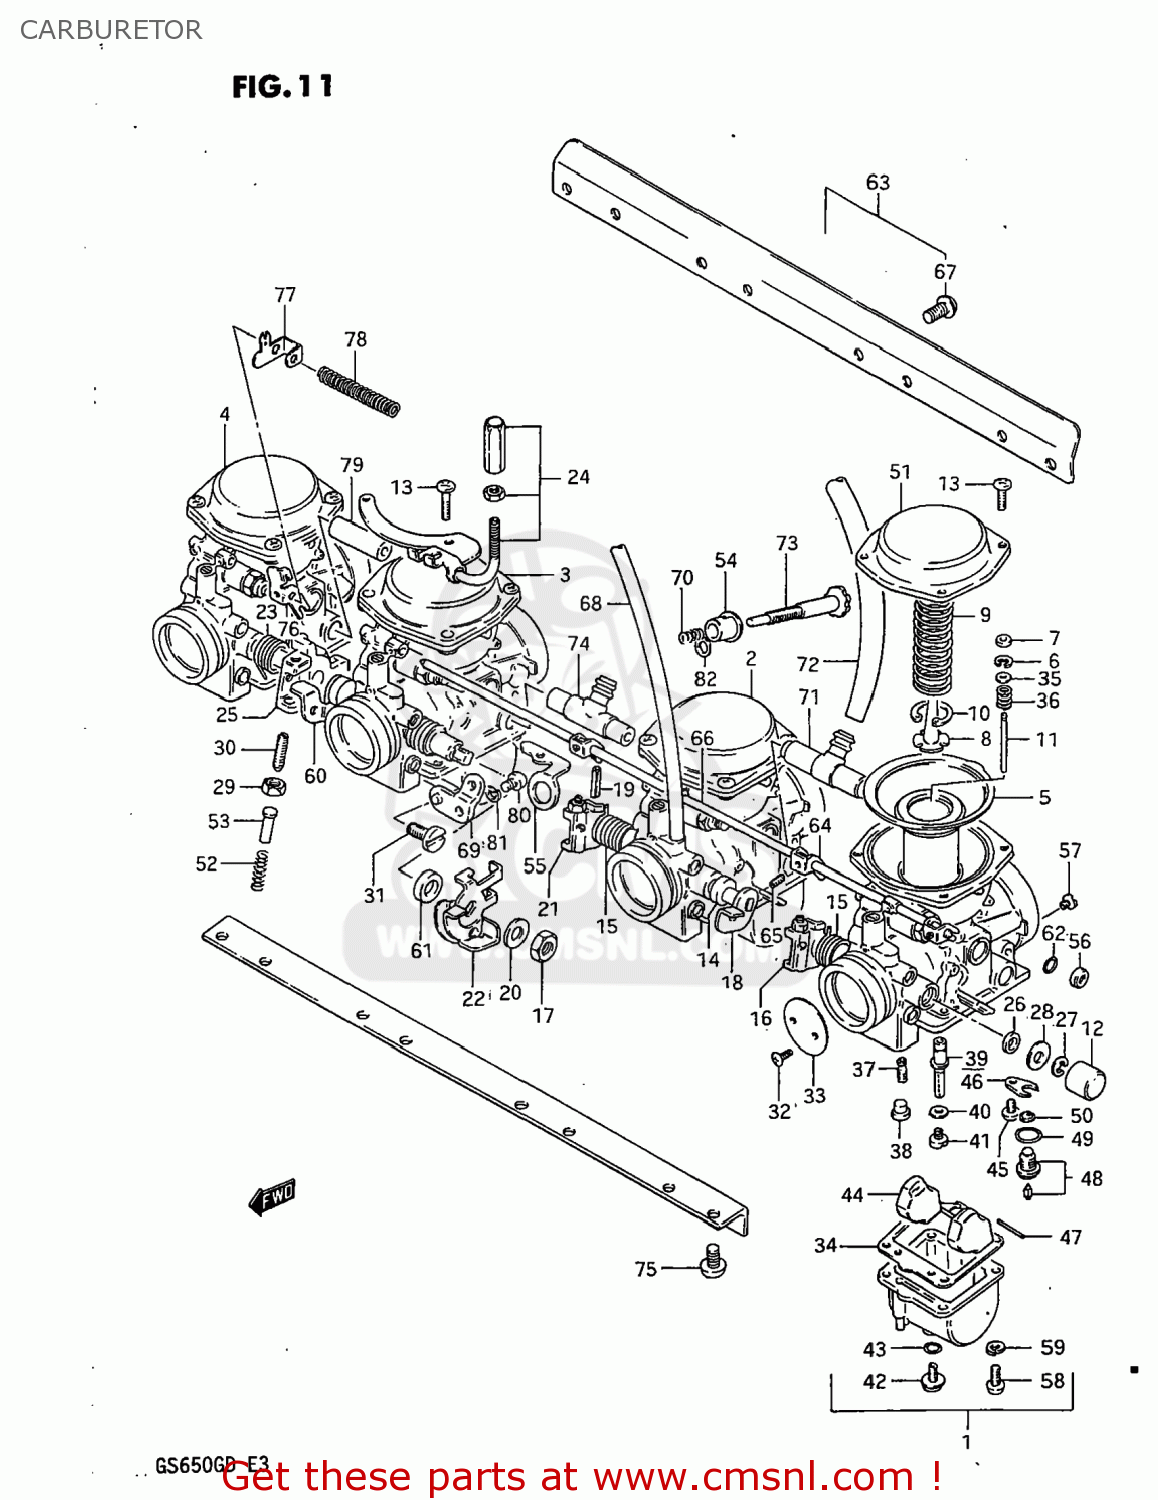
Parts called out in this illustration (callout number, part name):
1	CARBURETOR ASSEMBLY,LEFT
2	CARBURETOR ASSEMBLY
3	CARBURETOR ASSEMBLY
4	CARBURETOR ASSEMBLY
5	DIAPHRAGM
6	CLIP,NEEDLE
7	RING
8	HOLDER,GUIDE
9	SPRING
10	E RING
11	NEEDLE JET
12	CAP
13	SCREW
14	GASKET,THROTTLE SHAFT (NAS)
15	SPRING,THROTTLE SHAFT
16	SHAFT,THROTTLE
17	NUT 8MM
18	SHAFT,THROTTLE
19	PIN,THROTTLE SHAFT
20	WASHER
21	LEVER,THROTTLE SHAFT
22	LEVER ASSEMBLY,THROTTLE
23	SPRING,THROTTLE SHAFT
24	BRACKET,THROTTLE CABLE
25	SHAFT,THROTTLE
26	SEAL
27	E RING
28	GASKET,THROTTLE SHAFT (NAS)
29	NUT
30	SCREW
31	SCREW
32	SCREW
33	VALVE,THROTTLE (BUTTERFLY)
34	GASKET,FLOAT CHAMBER (NAS)
35	WASHER
36	SPRING
37	JET,PILOT(42.5)
38	PLUG,NEEDLE JET
39	JET,NEEDLE
40	WASHER,NEEDLE NOZZLE
41	JET,MAIN(110)
42	PLUG,DRAIN
43	GASKET (NAS)
44	FLOAT
45	SCREW 4X6
46	PLATE,NEEDLE VALVE FITING
47	PIN,FLOAT
48	VALVE ASSEMBLY,NEEDLE
49	O-RING,NEEDLE VALVE
50	FILTER
51	COVER,DIAPHRAGM
52	SPRING,THROTTLE SCREW
53	PIN,THROTTLE LEVER
54	BUSH
55	BRACKET,THROTTLE ADJUST
56	CAP,STARTER VALVE
57	JET
58	SCREW
59	LOCK WASHER
60	SHAFT,THROTTLE
61	WASHER
62	O RING
63	CARBURETOR ASSEMBLY
64	LEVER
65	SCREW
66	SHAFT,STARTER
67	SCREW
68	HOSE
69	BRACKET,THROTTLE ADJUST
70	SPRING
71	NIPPLE
72	HOSE
73	SCREW
74	NIPPLE,CARBURETOR
75	SCREW 6X12
76	LEVER,CHOKE CABLE
77	PLATE,CHOKE CABLE
78	SPRING,CHOKE CABLE
79	NIPPLE
80	SCREW
81	LOCK WASHER
82	WASHER
